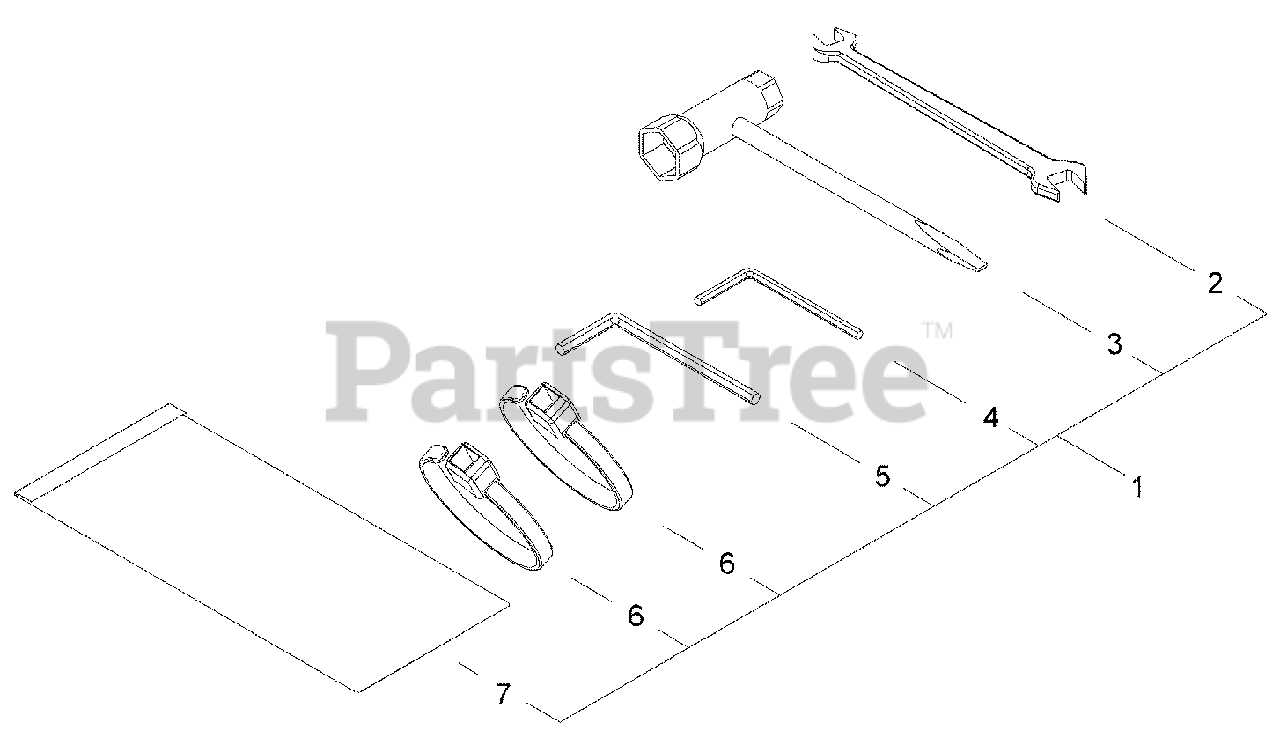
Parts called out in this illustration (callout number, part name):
1	TOOL KIT, SERVICE
2	SPANNER 8×10
3	T-WRENCH 16×13
4	WRENCH, ALLEN 4 MM
5	WRENCH, ALLEN 5 MM
6	TIE, CABLE
7	BAG, TOOL
